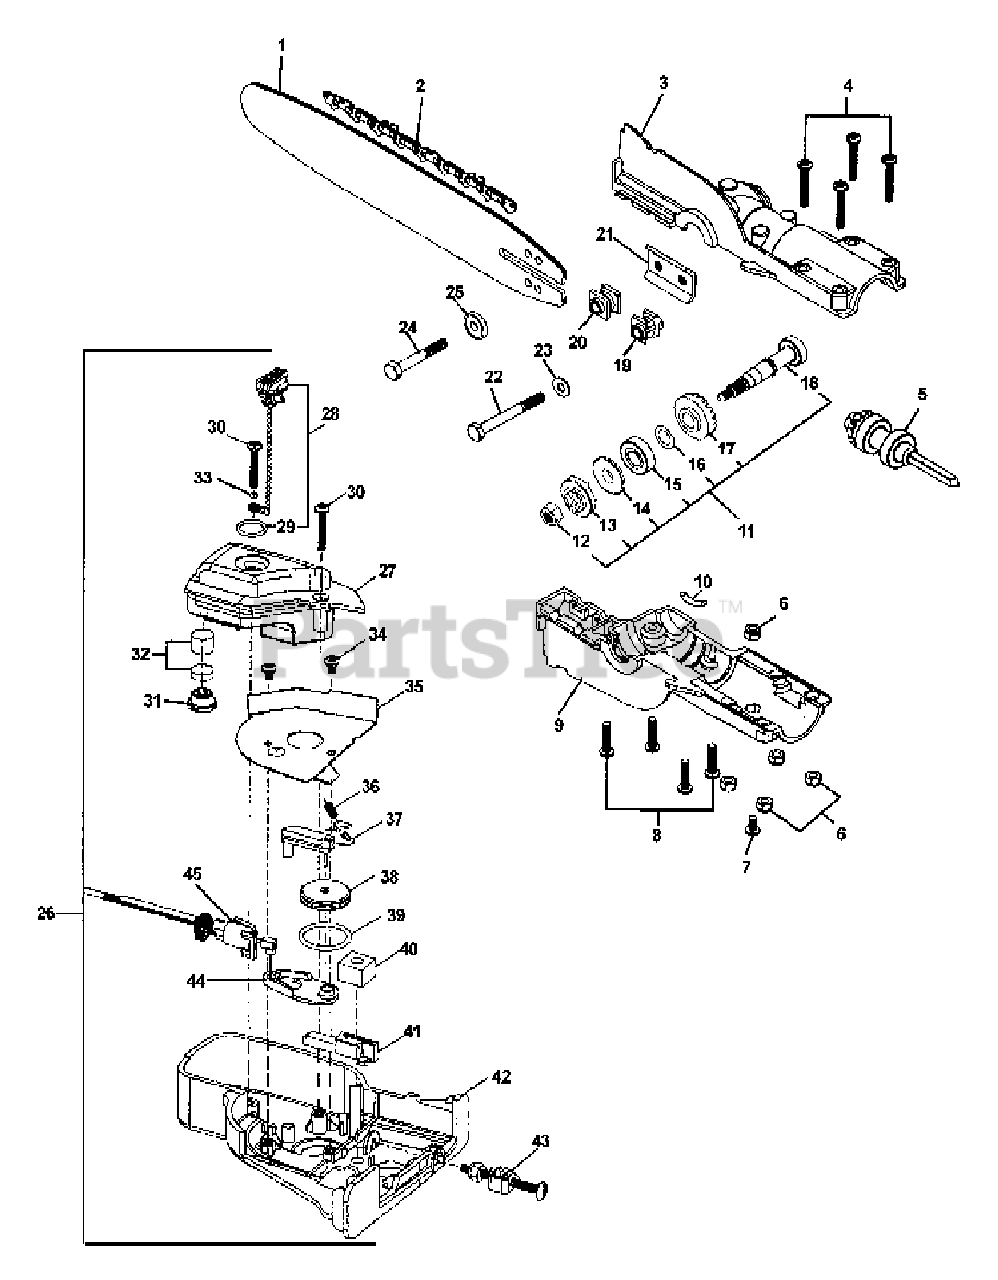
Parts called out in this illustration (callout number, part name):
1	GUIDE BAR - 12" (30cm)
2	SAW CHAIN - 12" (30cm)
3	CASE, GEAR - UPPER
4	SCREW - 10-24 X 1-1/4"
5	SHAFT GEAR ASSY
6	LOCKNUT - 10-24
7	SCREW
8	SCREW - 10-24 X 7/8"
9	CASE, GEAR - LOWER
11	GEAR SHAFT ASSY
13	SPROCKET, DRIVE
14	SPACER, SPROCKET
15	BEARING, BALL - 6001 DDU
17	GEAR - BEVEL
18	DRIVESHAFT SPROCKET ASSY
20	SPACER
21	BRACKET, GUIDE BAR
22	BOLT - 1/4-20 X 2-1/4"
24	SCREW - 1/4-20 X 1-3/4"
26	AUTO-OILER ASSY
27	OIL TANK ASSY
28	CAP ASSY
31	HOUSING, OIL FILTER
32	OIL FILTER ASSY
37	LINK, OILER IDLER
38	CAM, OIL PUMP
40	SPACER
41	PIPE, OIL OUTLET
42	COVER, OIL PUMP
43	TENSIONER KIT
44	LINK, OILER DRIVE
45	AUTO-OILER ASSY
